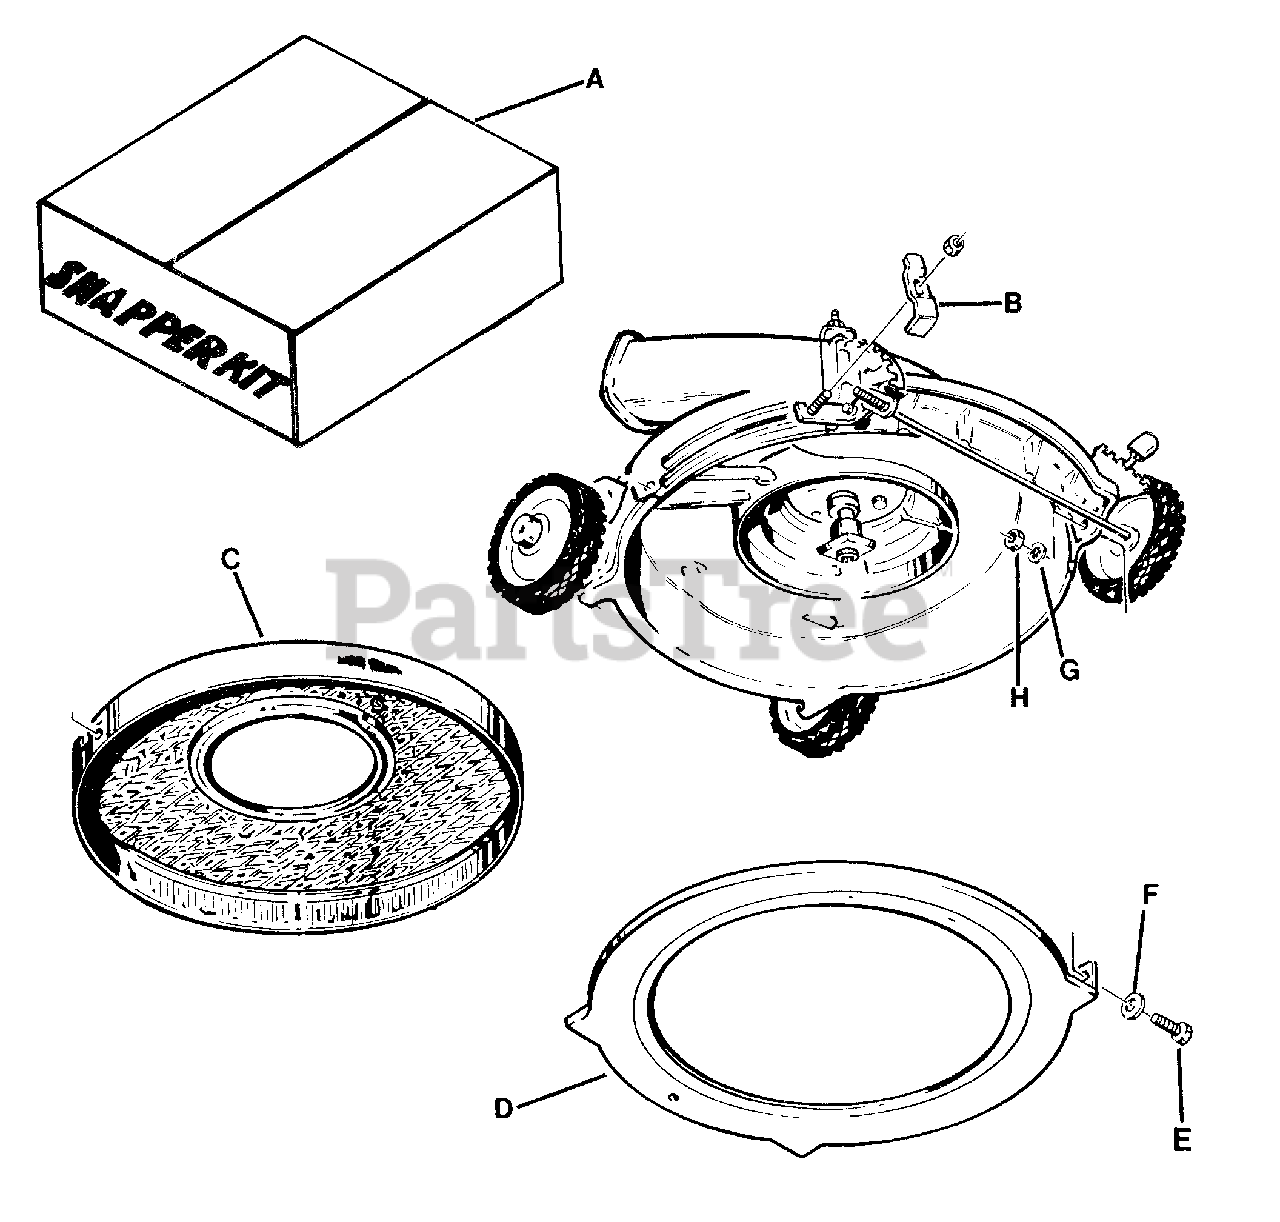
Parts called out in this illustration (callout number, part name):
A	KIT, V18 Snapperizer (complete)
B	BRACKET, V18 Bottom Plate
C	SCREEN, V18 Snapperizer
D	PLATE, V18 Bottom
E	SCREW, 1/4-28 x 3/4" Hex Head Cap, Grade 5
F	WASHER, 1/4" SAE Flat
G	WASHER, 1/4" Internal Tooth Lock
H	NUT, 1/4-28 Hex
